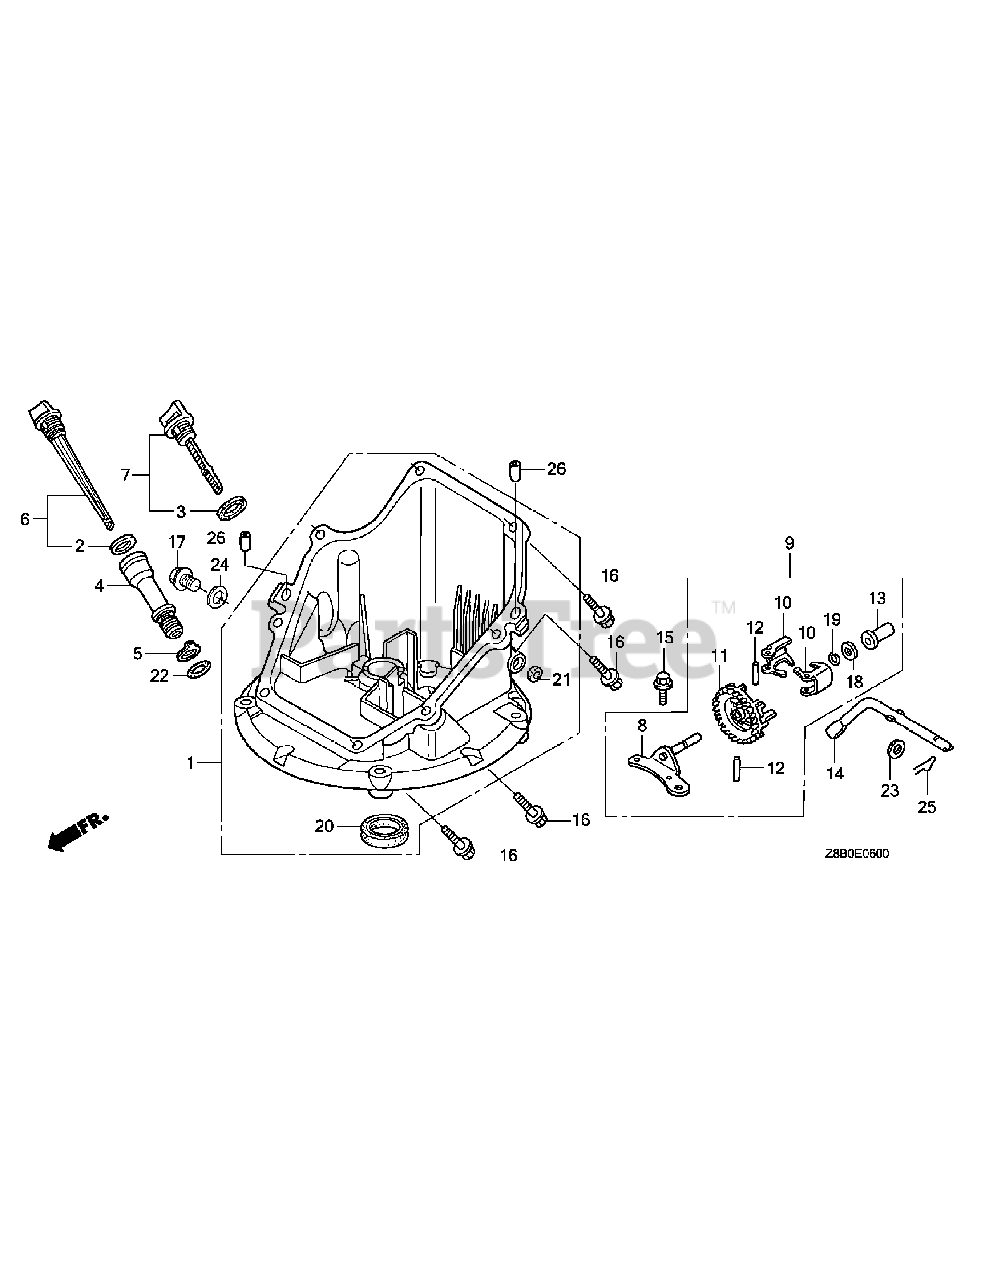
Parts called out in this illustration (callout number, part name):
1	PAN ASSY., OIL
2	PACKING, OIL FILLER CAP
4	EXTENSION, OIL FILLER
5	WASHER, EXTENSION LOCK
6	GAUGE ASSY., OIL LEVEL
8	SHAFT COMP., GOVERNOR HOLDER
9	GOVERNOR ASSY.
10	WEIGHT, GOVERNOR
11	HOLDER, GOVERNOR WEIGHT
12	PIN, GOVERNOR WEIGHT
13	SLIDER, GOVERNOR
14	SHAFT, GOVERNOR ARM
15	BOLT, FLANGE, 6X14(CT200)
16	BOLT, FLANGE, 6X25(CT200)
17	BOLT, DRAIN PLUG, 12X15
18	WASHER, THRUST, 6MM
19	CLIP, GOVERNOR HOLDER
20	OIL SEAL, 28X41.25X6
21	OIL SEAL, 6X11X4
22	O-RING, 14.8X2.4(ARAI)
23	WASHER, PLAIN, 6MM
24	WASHER, DRAIN PLUG, 12MM
25	PIN, LOCK, 8MM
26	DOWEL PIN, 8X20
